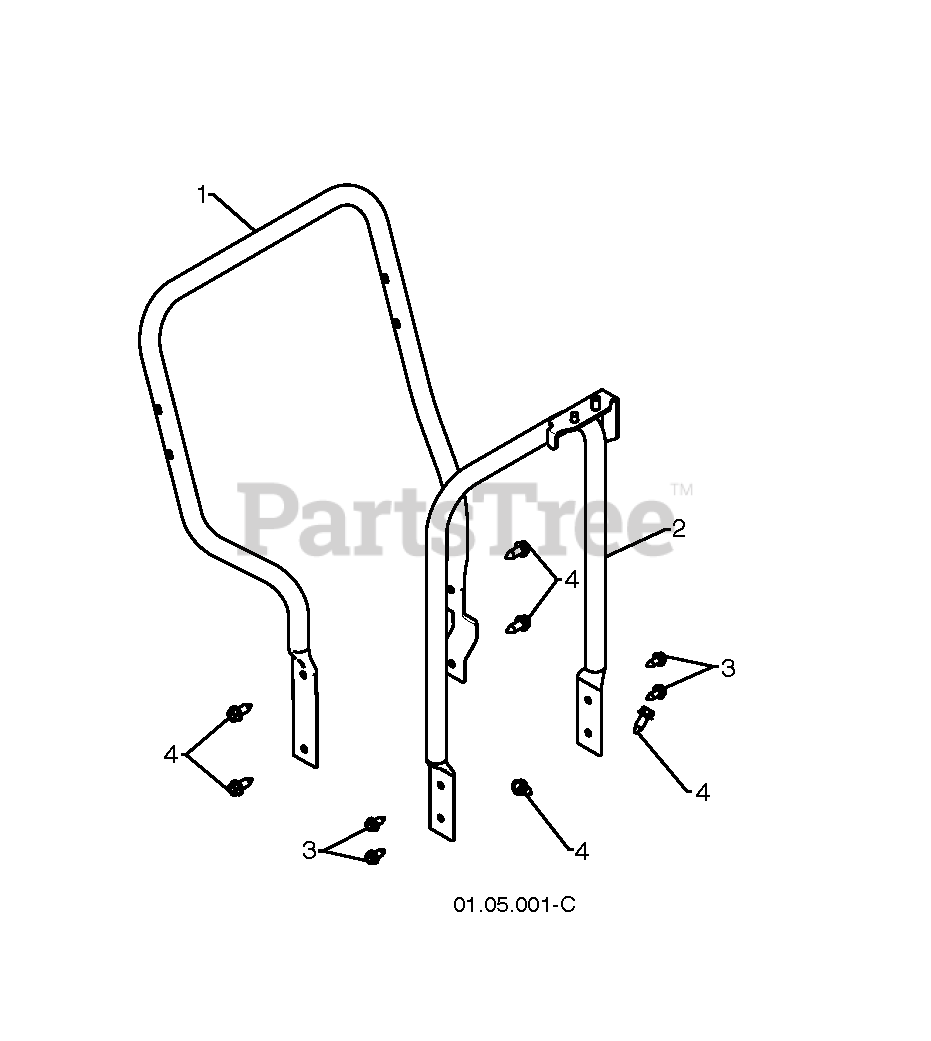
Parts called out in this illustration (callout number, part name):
1	RP TUBE.LOWER.PNT.BLACK
2	TUBE.LOWER.BLACK
3	BOLT.HEX.HD.WASHER.5/16-18X.75
4	SCREW 3/8-16X1
